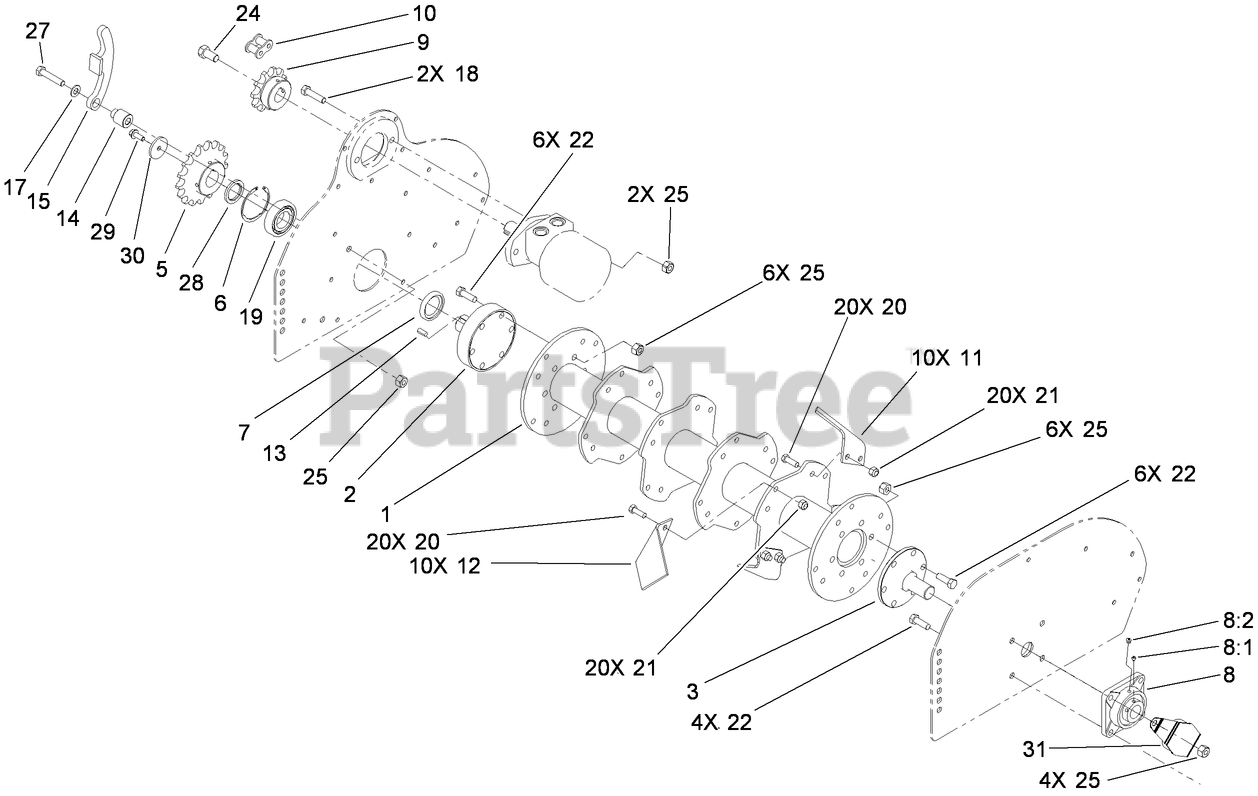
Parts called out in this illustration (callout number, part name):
2	SHAFT-DRIVE
3	PLATE-DISC
5	GEAR-17 TOOTH
6	RING-RETAINING
7	SEAL-SHAFT
8	BEARING ASM
8:1	SCREW-SET, HSH
8:2	FITTING -GREASE
9	SPROCKET ASM-WELDED
10	CHAIN-ROLLER
11	BLADE-LEFT
12	BLADE-RIGHT
13	KEY-SQUARE
14	BRACING-TUBULAR
15	TIGHTENER-CHAIN
17	WASHER-FLAT
18	SCREW-HH
19	BEARING-BALL
20	SCREW-HH
21	NUT-LOCK, INSERT
22	SCREW-HH
24	SCREW-HH
25	NUT-LOCK, NI
27	SCREW-HH
28	SPACER-BEARING
29	SCREW-HHF
30	PLATE-COVER, SPROCKET
31	COVER-BEARING
